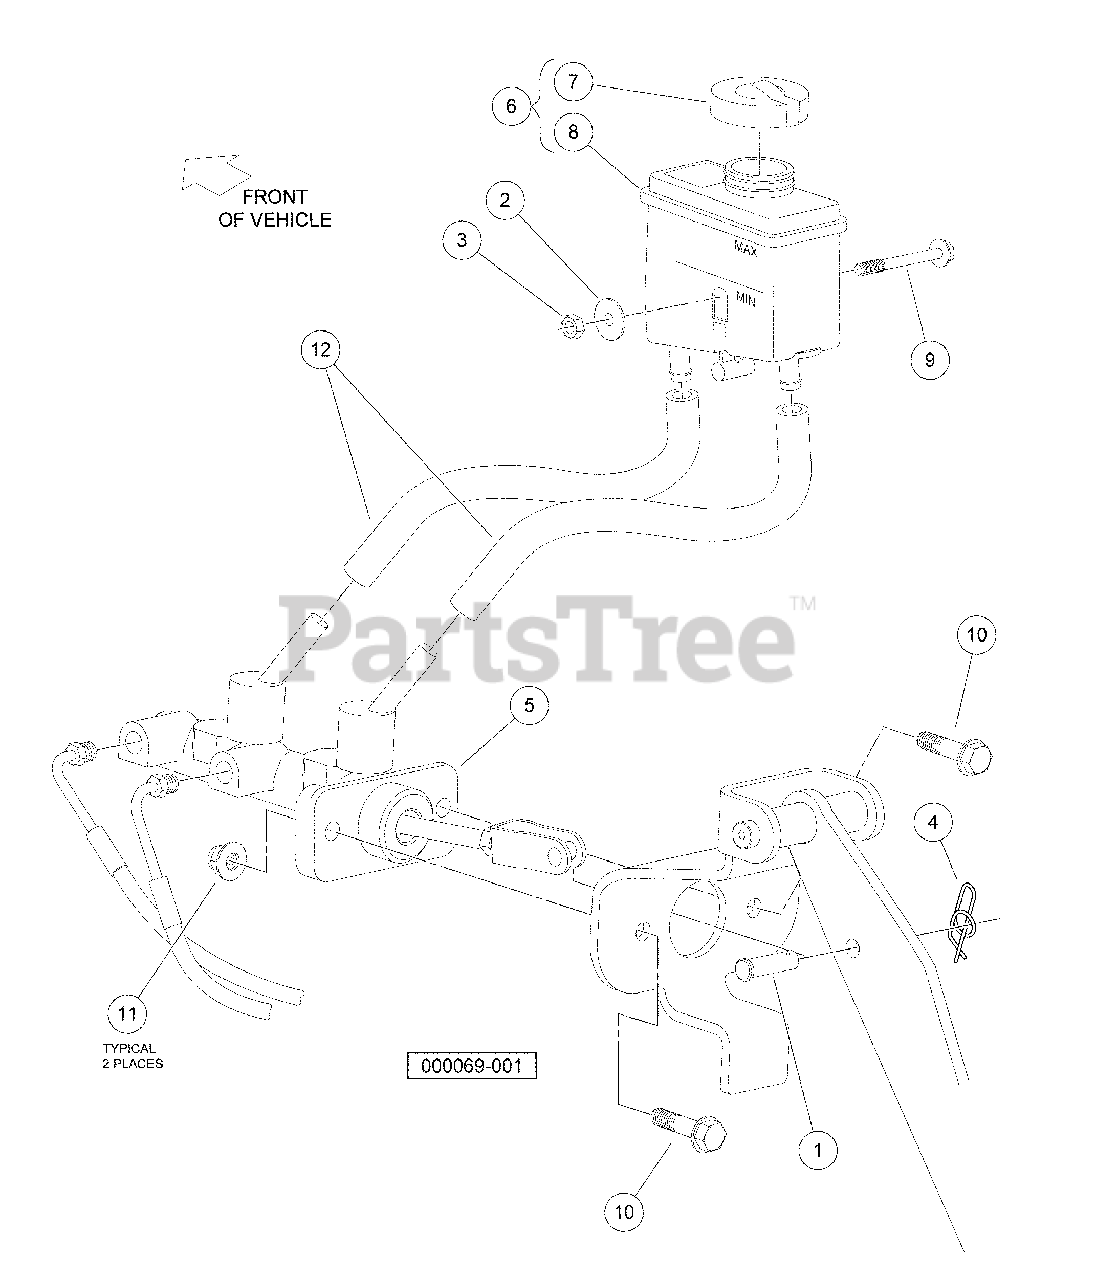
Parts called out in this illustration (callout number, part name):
1	Clevis Pin, 5/16 X 1
2	Washer, 1/4" Type B Flat
3	Locknut, M6-1.00 Nylon Insert
5	Cylinder, Master, Tandem
6	Assembly, Reservoir, Remote
7	Filler Cap Asm
8	Reservoir, Brake Fluid, Without Cap
9	Bolt, M 6 X 1.0 X 65 Hex, Flange, Head, Black
10	Bolt Flanged Head, M8 X 1.25 X 35
11	Lock Nut, Flg M8 X 1.25 Nylon
12	Line, Reservoir, Brake
